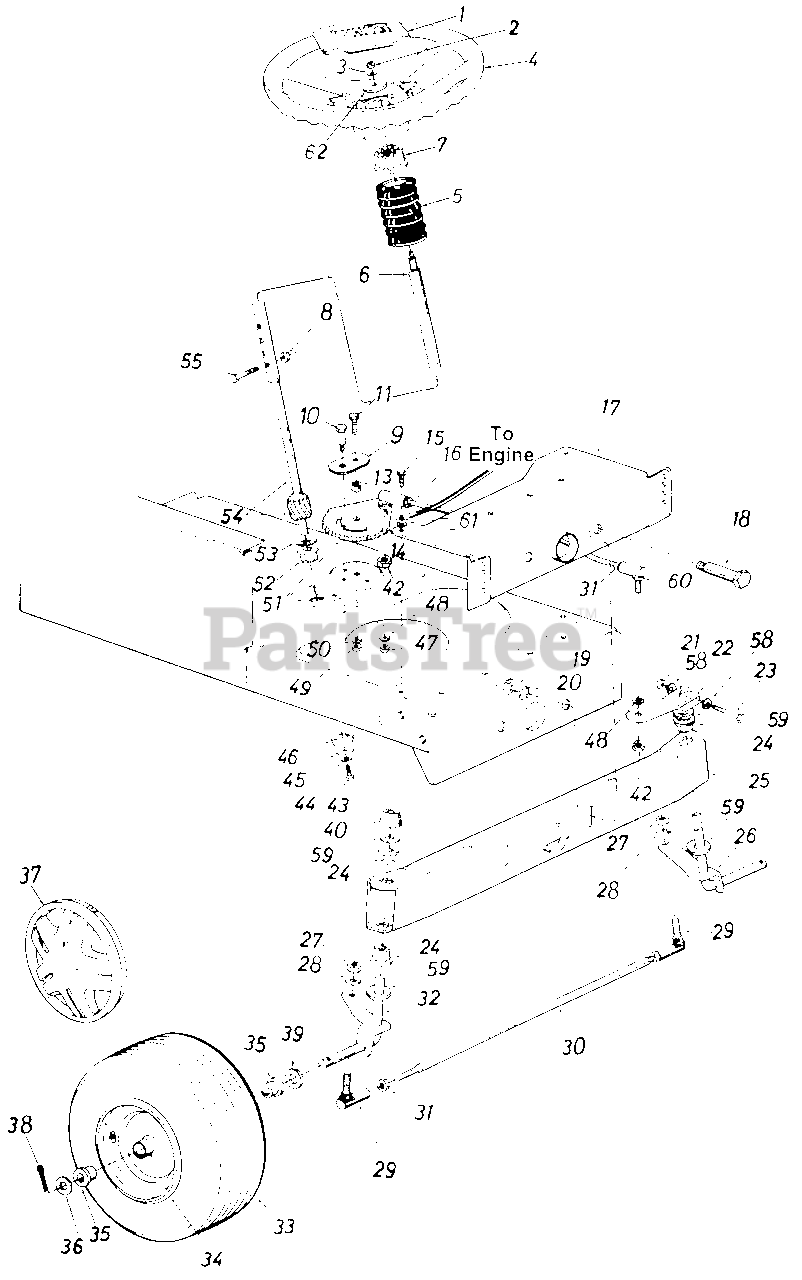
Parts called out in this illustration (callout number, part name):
1	Steering Wheel Insert
2	Hex L-Nut 5/16-24 Thd.
3	Belleville Wash. .345" I.D.
4	Steering Wheel
5	Steering Bellow
6	Steering Column Ass'y.
7	Steering Wheel Adapter
8	Hex L-Nut 1/4-20 Thd.
9	Retainer Plate
10	Shoulder Bolt .437" Dia. x .35" Lg. 5/16-18 Thd.
11	Hex Bolt 3/8-24 x 1.0" Lg. (Grade 5)
13	Spacer .380" I.D. x .625" O.D. x .227"
14	L-Wash. 318" I.D.
15	Hex Wash. Hd. Self-Tap Scr.
16	Steering Drag Link
17	Front Pivot Brkt.
18	Shoulder Bolt .498" .,ia. x 2.04" Lg. 3/8-16 Thd.
19	Hex Nut 3/8-16 Thd.
20	L-Wash. 318" I.D.
21	Hex Cent. L-Nut 5/16-24 Thd.
22	Steering Arm Front Axle
23	Hex Bolt 5/16-24 x 2.00" Lg. (Grade 5)
24	Hex Flg. Brg. .634" I.D.
26	Front Axle Ass'y.-L.H.
27	Hex Nut 3/8-24 Thd.
28	L-Wash. 3/8" I.D.
29	Ball Joint 3/8-24 Thd.
31	Hex Jam Nut 3/8-24 Thd.
32	Front Axle Ass'y.-R.H.
34	Front Wheel Rim Only
35	Flange Bearing
36	Fl-Wash. .635" I.D. x 1.59" O.D.
38	Cotter Pin 1/8" Dia. x 1.25" Lg.
39	Fl-Wash. .640" I.D. x .24" O.D.
40	Push Cap 5/8" Dia. Rod
42	Hex Jam Nut 3/8-24 Thd.
43	Hex L-Bolt 5/16-18 x .62"
44	L-Wash. 5/16" I.D.
45	Fl-Wash. .33" I.D. x 1.25" O.D.
46	Spacer (Plastic)
47	Hex Nut 3/8-24 Thd.
48	L-Wash. 3/8" I.D.
49	Hex Nut 5/16-18 Thd.
50	L-Wash. 5/16" I.D.
51	Steering Gear Segment
52	Hex Flg. Brg. .634 I.D.
53	Fl-Wash. (Hardened)
54	Steering Shaft Lower
55	Hex Bolt 1/4-20 x 1.31" Lg.
58	Wave Wash. .32" I.D. x .62"
59	Fl-Wash. (Hardened)
60	Drag Link Ball Joint 3/8-24 Thd.
61	Ext. L-Wash. 5/16" I.D.
62	Fl-Washer
